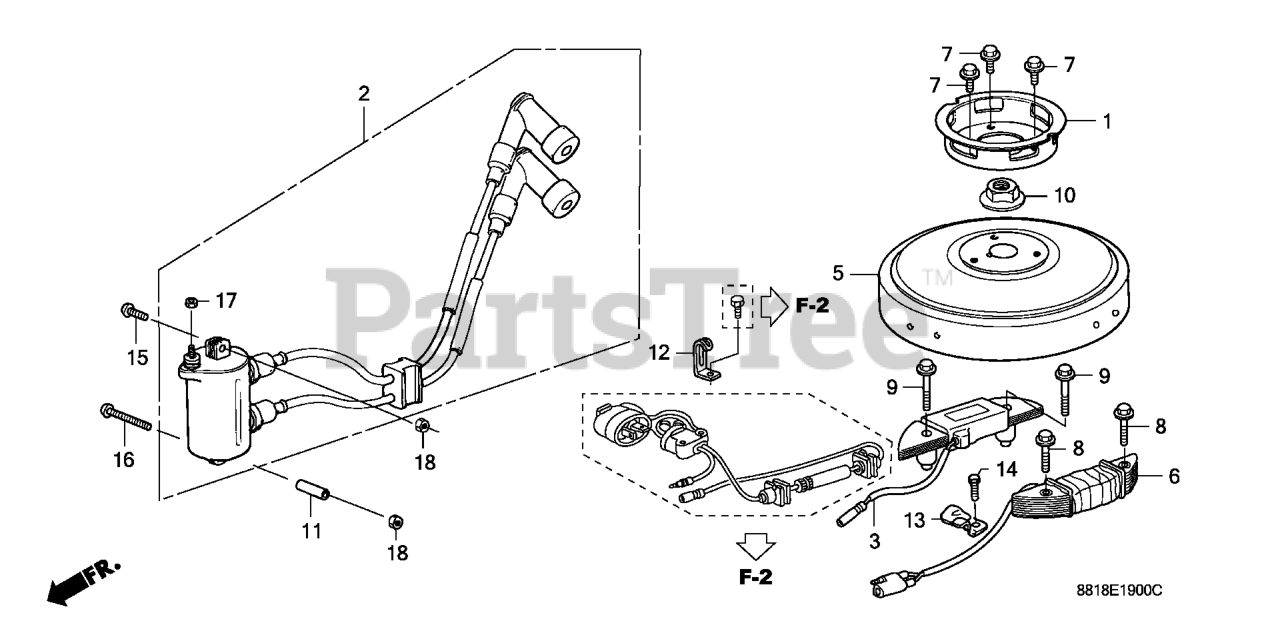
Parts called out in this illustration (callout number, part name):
1	PULLEY, STARTER
2	COIL ASSY., C.D.I. IGNITION
3	COIL ASSY., EXCITER
5	FLYWHEEL *TBLACK* (BLACK)
6	COIL ASSY., CHARGE (DC12V/55W)
7	BOLT, FLANGE (6X12)
8	BOLT, FLANGE (6X28)
9	BOLT, FLANGE (6X35)
10	NUT, SPECIAL (14MM)
11	COLLAR, DISTANCE
12	CLIP, TUBE
13	CLIP, WIRE
14	SCREW, PAN (6X12)
15	SCREW, PAN (6X28)
16	SCREW, PAN (6X50)
17	NUT, HEX. (5MM) (NOT AVAILABLE)
18	NUT, HEX. (6MM)
